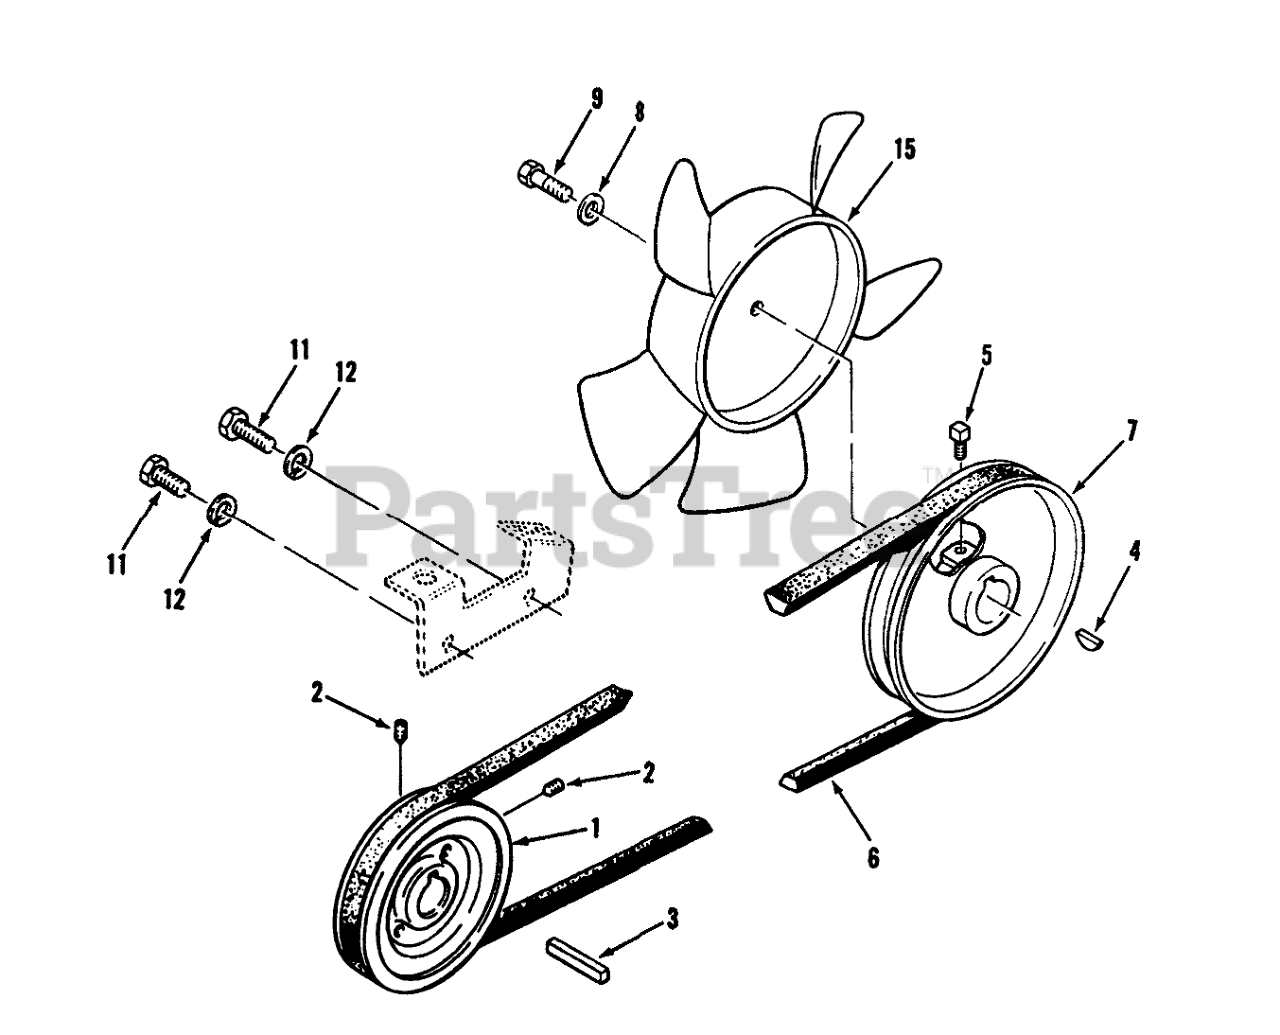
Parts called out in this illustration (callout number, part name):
1	PULLEY
2	SCREW-SET, HSH
4	KEY-WOODRUFF
5	SCREW-SQH
6	BELT-V
7	PULLEY
8	WASHER
9	SCREW-HH
11	SCREW-HH, LOCK
12	WASHER-PLAIN
15	NYLON FAN-L-CW
